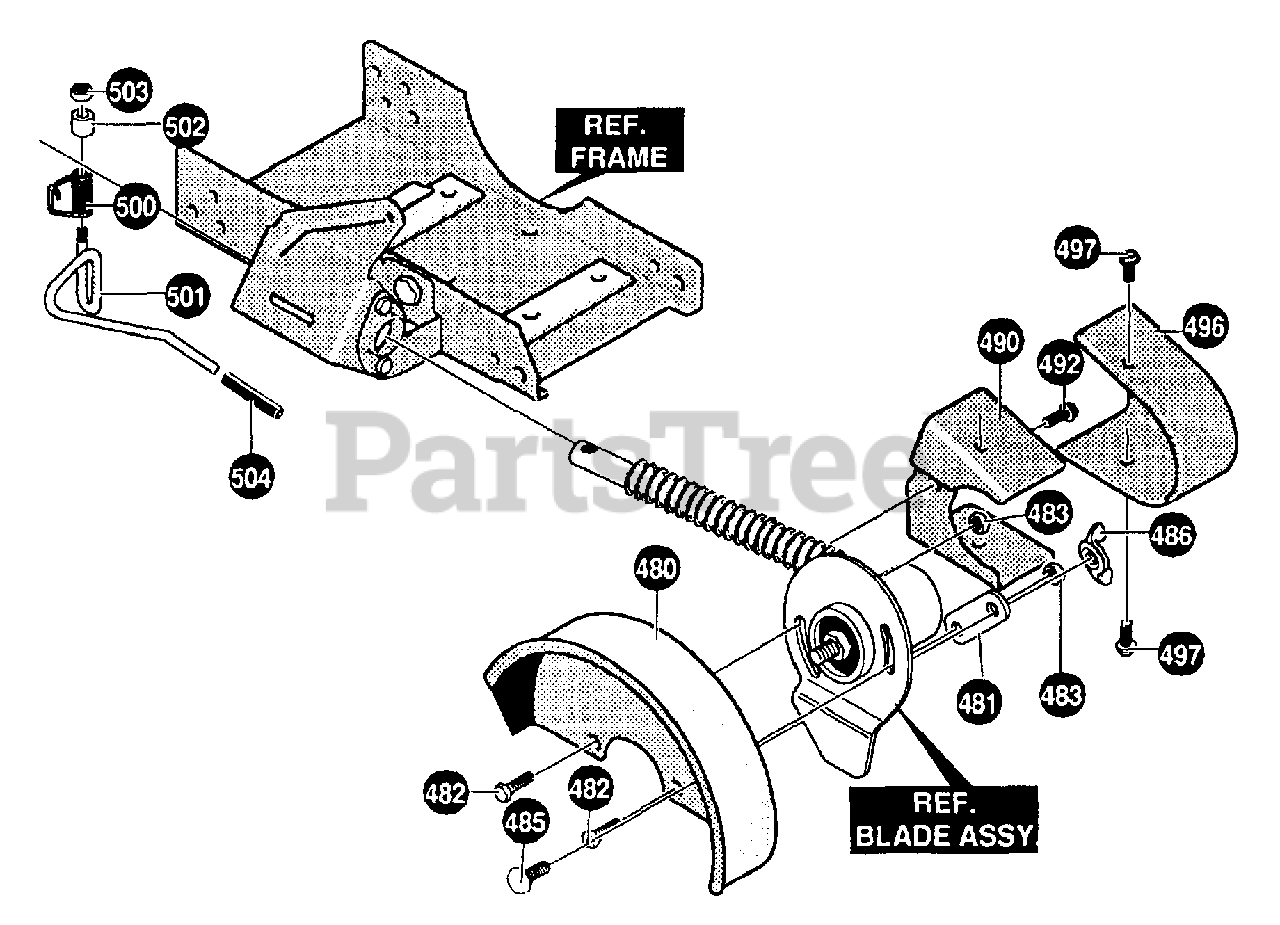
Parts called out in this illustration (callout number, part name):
480	GUARD, BLADE
481	BAR, LOCKING
482	SCREW, 5/16-18X.75 IN.
483	NUT, 5/16-18 REGHEXCTRLK
485	BOLT, 5/16-18X.75 CARR
490	GUIDE, BELT FRONT
492	SCREW, 1/4-20X.50
496	COVER, QUILL PULLEY
497	SCREW, 10-24X.38
500	SPRING, INDEX
501	LEVER, INDEX
502	SPACER, SLEV .33X.50X.25
503	NUT, 5/16-18 REGHEXCTRLK
504	GRIP, INDEX LEVER
